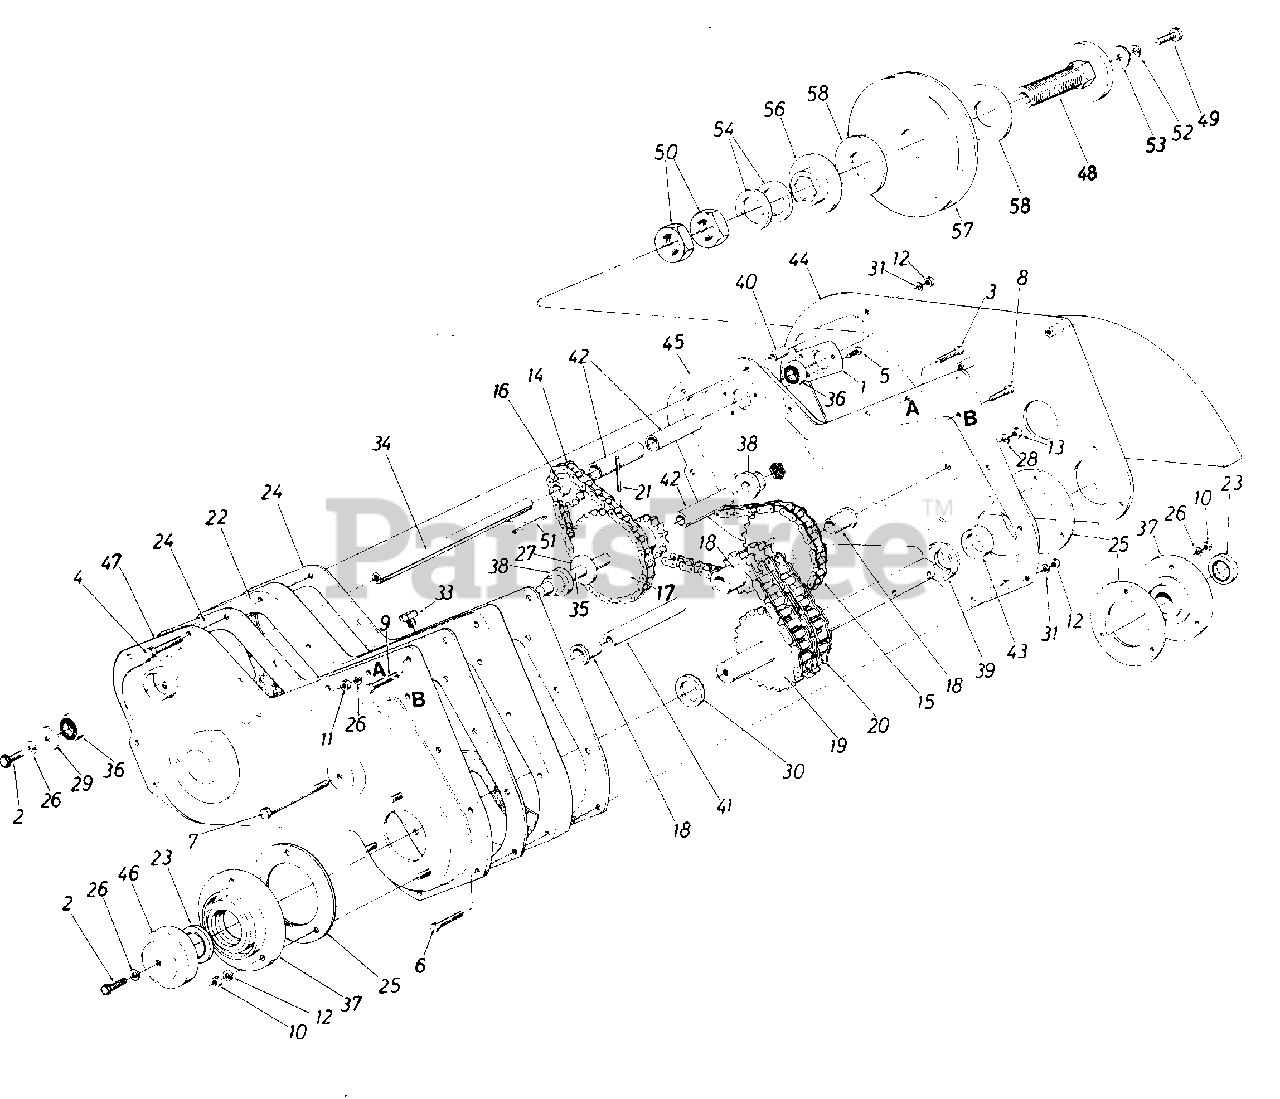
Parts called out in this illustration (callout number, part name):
1	Bearing Housing 1-3/8" Dia.
2	Hex Bolt 5/16-18 x .88" Lg. Spec.
3	Hex Bolt 5/16-18 x 1.50" Lg.*
4	Hex Bolt 1/4-20 x 2.75" Lg.*
5	Hex Wash. S-Tap. Scr. 1/4-20 x .50" Lg.
6	Hex Bolt 1/4-20 x 1.50" Lg.*
7	Hex Bolt 3/8-16 x 4.5" Lg.
8	Hex Wash. Hd. Bolt 1/4-20 x 1.5" Lg.
9	Hex Wash. TT-Tap Scr. 5/16-18 x 1.751' Lg.
10	HexCent. L.-Nut5/16-18 Thd.
11	Hex Nut 5/16-18 Thd.*
12	Hex ut 1/4-20 Thd.*
13	Hex Nut 3/8-16 Thd.*
14	#41 Chain 1/2" Pitch x 34 Links- Endless
15	#42 Chain 1/2" Pitch x 48 Links- Endless
16	Sprocket 10 Tooth .500" Pitch
17	10 & 28 Teeth Sprocket Ass'y.
18	18-2 & 28 Sprocket Sleeve Ass'y
19	18-2 Sprocket Shaft Ass'y.
20	#50-2 Chain 5/8" Pitch x 28 Links- Endless
21	Spring Pin Spir. 1/4" Dia. x 1.50" Lg.
22	Spacer Block - Tiller Housing
23	Oil Seal Double Lip-1-1/4" Dia.
24	Gasket for Tiller Housing
25	Gasket for Brg.-Housing
26	L.-Wash. 5/16" I.D.*
27	Fl.-Wash. .640" I.D. x 1.24" O.D.
28	L.-Wash. 3/8" I.D. Heavy Duty
29	Fl.-Wash. .344" I.D. x.1.125"
30	Special Washer
31	L.-Wash. 1/4" I.D.*
33	Vent Plug
34	Jack Shaft .525" I.D. x 7.78 " Lg.
35	Sprocket Shaft .63" Dia. x 5.0" Lg.
36	Ball Brg. .62" I.D. x 1.38" O.D.
37	Bearing Housing-1-1/4"
38	Hex Flange Brg.
39	Spacer 1.25" I.D. x 2.0" O.D.
40	Spacer .28" I.D. x .62" O.D. x . 90" Lg .
41	Spacer.38" I.D. x .62" O.D. x 3.44" Lg.
42	Spacer.62" I.D. x.88" O.D. x 1.56" Lg.
43	Spacer 1.25" I.D. x 1.62" O.D. x.50" Lg.
46	Dust Cap .320" Dia. Hole
49	Hex Bolt 5/16-18 x 1.25" Lg. Grade 5
50	Hex Jam Nut 1.0-14 x 28 Thd.
51	Sq. Key 3/16 x 1.50" Lg.
52	L.-Wash. 5/16" I.D.*
53	Fl.-Wash. .344" I.D. x 1.125" O.D.
54	Spring Bell Wash. 1.0" I.D. x 2.0" O.D.
56	F loating Disc 3-1/4" O.D. x 1.0" I.D.
57	5/8 V-Pulley 1.50" I.D. x 6.50"
58	Friction Pad 3-1/4" O.D. x 1-3/8" I.D.
